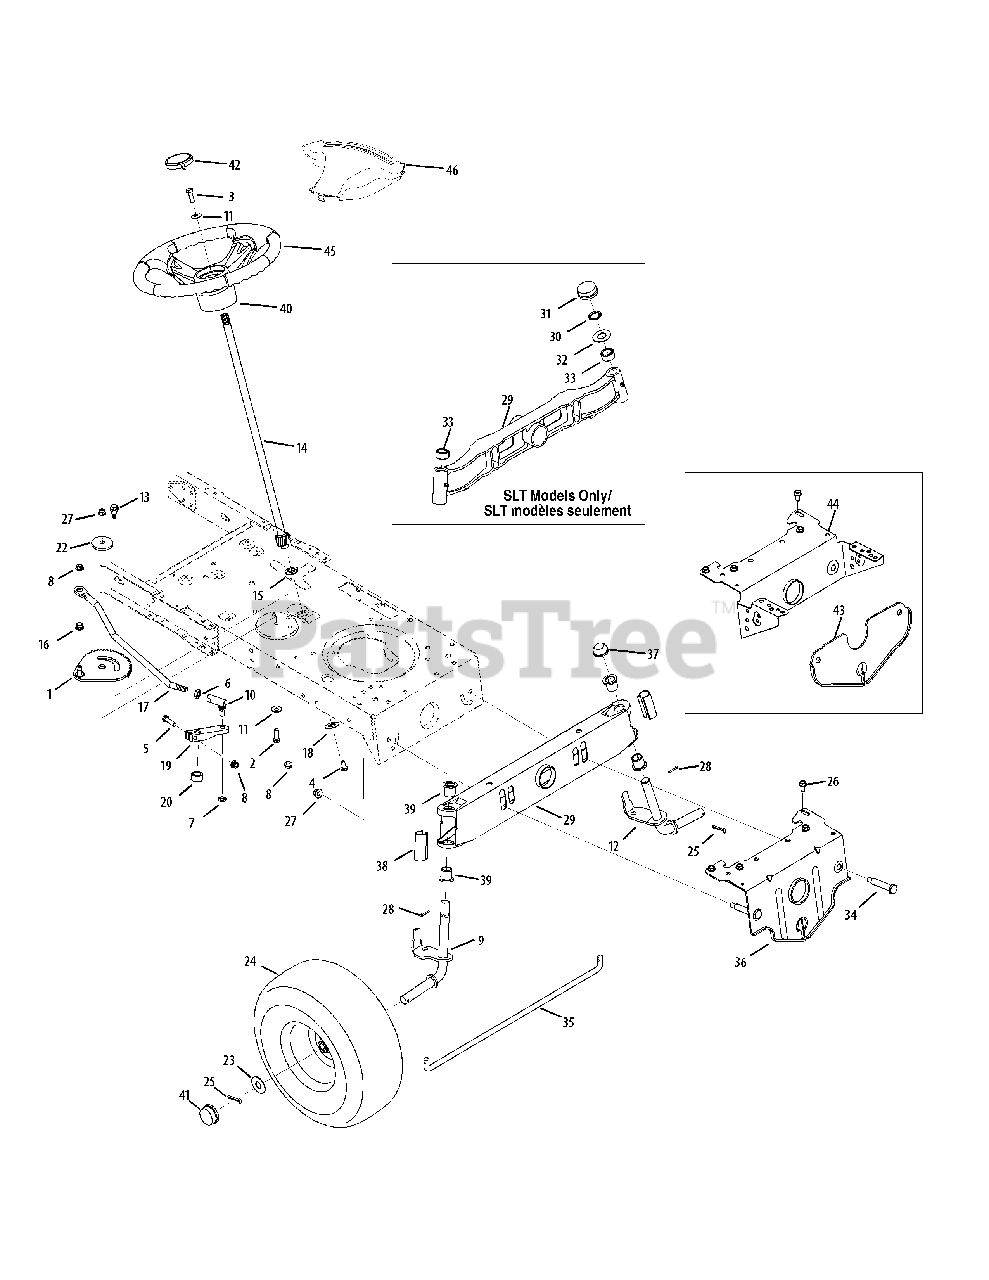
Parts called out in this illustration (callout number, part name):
1	Steering Gear Assembly
2	Hex Hd. Cap Scr 3/8-16 x 1,00 Gr. 5
3	Hex Screw 5/16-18 x 1.00 Special
4	Machine Screw 5/16-18 x .75
5	Hex Screw 5/16-18 x 1.75" Lg.
6	Hex Jam Nut 7/16-20
7	Hex Cent-L Nut 3/8-24 Gr. B
8	Flange Locknut 5/16-18 Gr. F, Ny lon
9	Axle Assembly, RH
10	Ball Joint, 7/16 - 20
11	Cupped Washer .345 ID x .88 OD x .060
12	Axle Assembly, LH
13	Shoulder Screw .435 x .3485, 5/16-18
14	Steering Shaft, 5/8 Spline x 21.86
15	Hex Flange Bear ing 5/8
16	Bushing .375 ID x .5
17	Steer ing Drag Link
18	Cap, 1.25 x .16
19	Steering Block
20	Spacer .710 ID x .125 OD x .56
22	Shoulder Spacer
23	Flat Washer .781 ID x 1.59 OD Special
24	Wheel Assembly Complete
25	Cotter Pin 5/32 x 1.25
26	S-Tapp Scr 5/16-18 x .75
27	Flange Lock-Nut 3/8-16 Gr. F, Ny lon
28	Cotter Pin 1/8" Dia x .75
30	Push Nut 3/4"
31	Axle End Cap
32	Flat Washer .78 x 1.59 x .060
33	Spacer .71 x .125 x .56
34	Shoulder Screw .500 x 2.380, 3/8-16
35	Tie Rod
36	Pivot Bar Bracket
37	Push Cap, .750
38	Axle End Cap, Standard
39	Flange Bear ing .760 ID x .937 OD
40	Steering Wheel, Standard Grip
41	Plastic Hub Cap
42	Steering Wheel Cap (sprig logo)
45	Steering Wheel
46	Steering Wheel Cover
